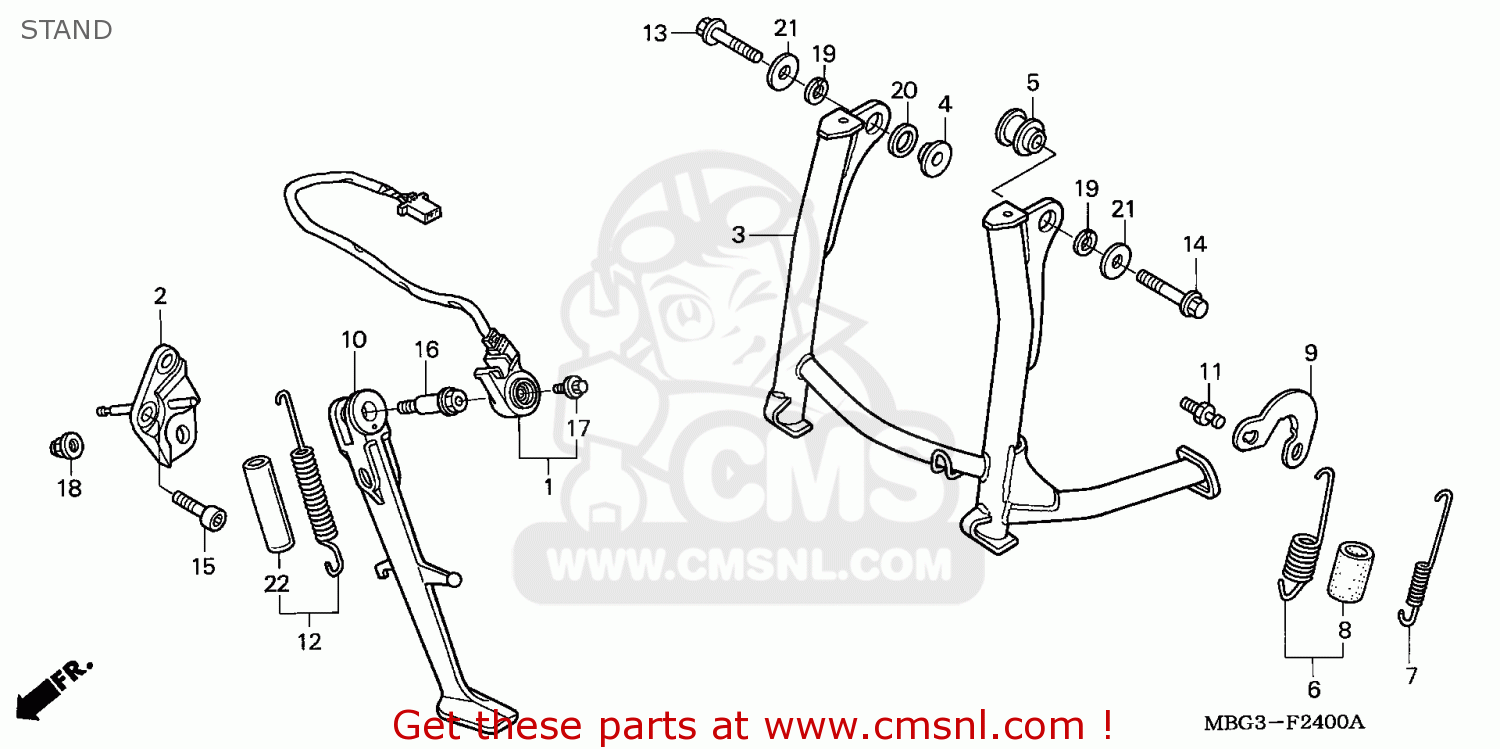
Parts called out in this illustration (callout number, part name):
1	SET,SIDE STAND SW
2	BRKT,SIDE STAND
3	STAND COMP,MAIN.
4	COLLAR,R MAIN STA
5	COLLAR,L MAIN STA
6	SPRING ASSY,MAIN
7	SPG,MAIN STAND SU
8	RUBBER,MAIN STAND
9	PLATE,MAIN STAND
10	BAR,SIDE STAND
11	HOOK,SPG.MAIN STA
12	SPG.ASSY,SIDE STA
13	BOLT,FLANGE,10X32
14	BOLT,FLANGE,10X50
15	BOLT SOCKET 10X26
16	BOLT,SIDE STAND P
17	BOLT,SPECIAL 6X16
18	NUT,SIDE STAND
19	WASHER 24X18,SPG
20	WASHER,18.5MM
21	WASHER,PLAIN,10MM
22	V.TUBE 14X18X60
